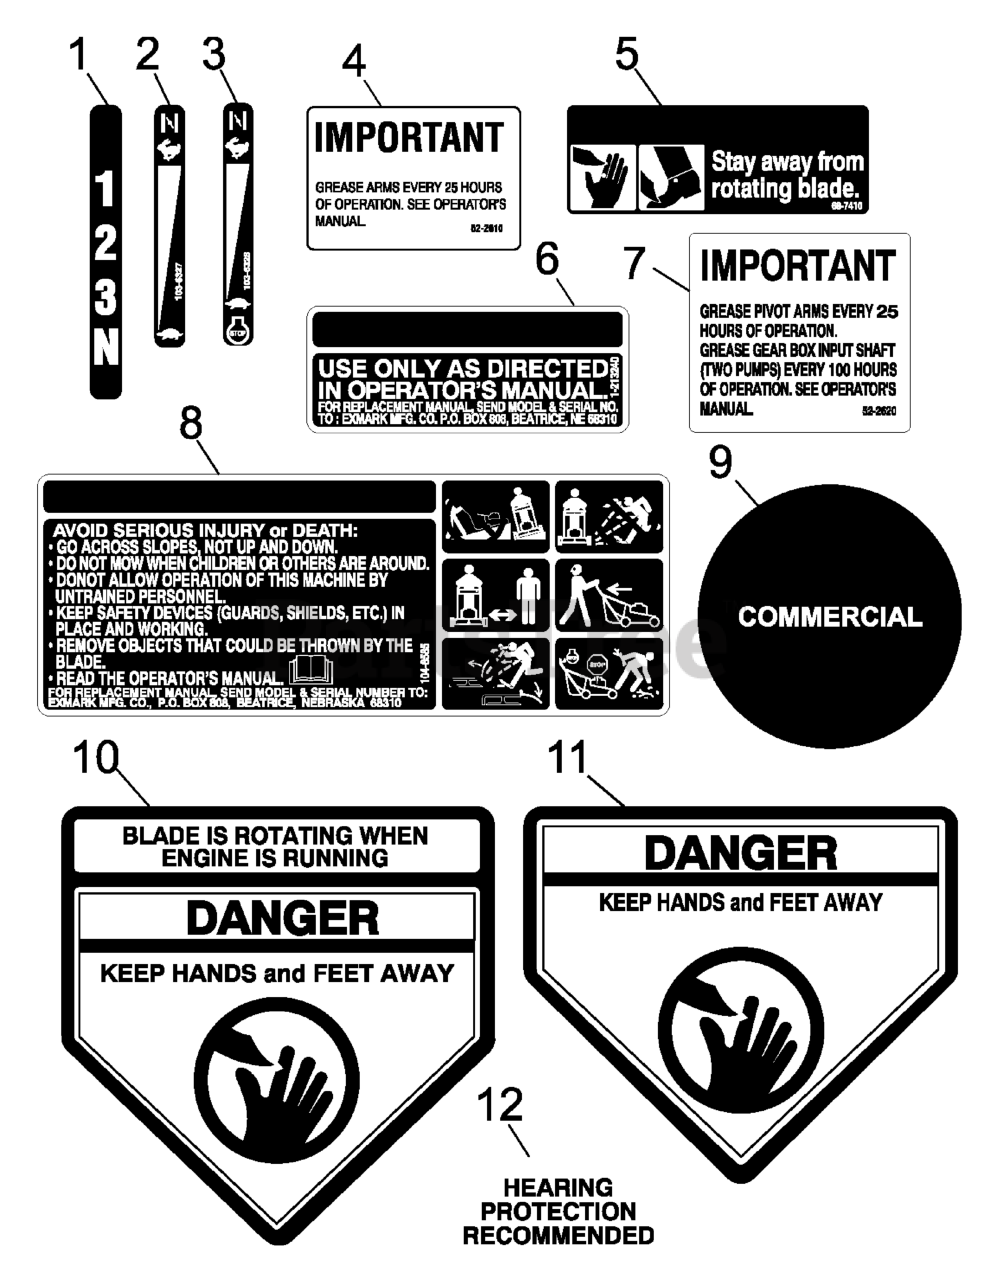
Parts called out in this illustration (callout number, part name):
1	DECAL,SHIFTER
2	DECAL,THROTTLE/CHOKE
3	DECAL-THROTTLE / CHOKE
4	LABEL-GREASE, HP
5	DECAL-BLADE
7	Label, Grease
8	DECAL-WARNING
9	DECAL-RECOIL
10	DECAL-DANGER
11	DECAL-DANGER
12	DECAL-PROTECTION, HEARING
